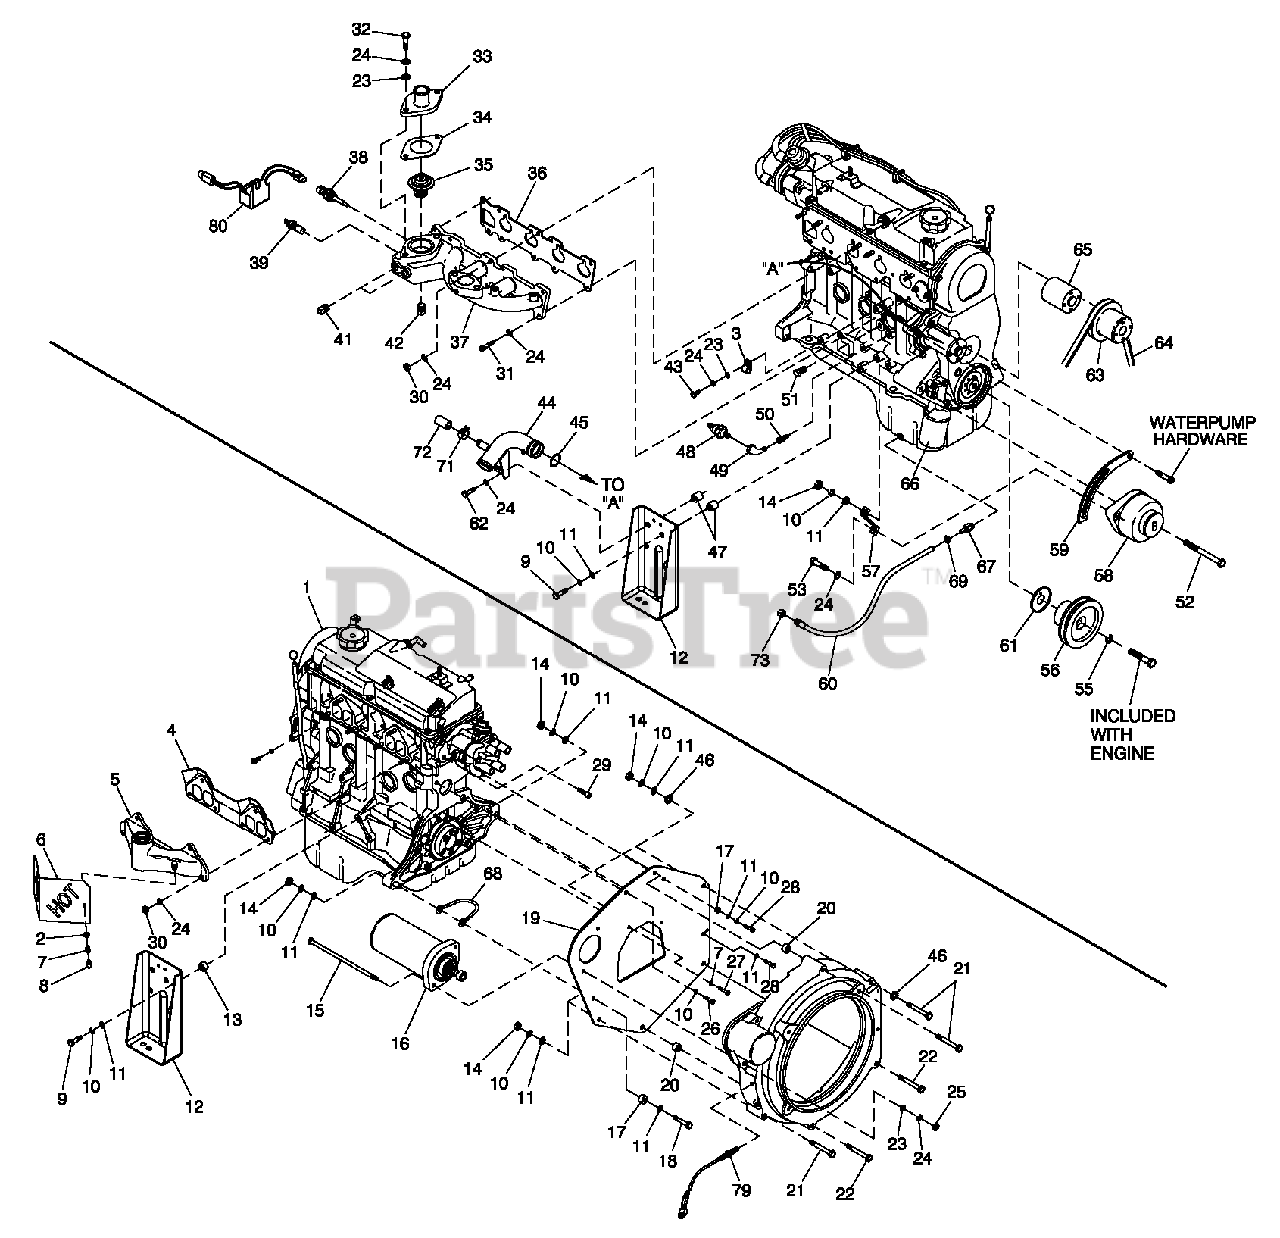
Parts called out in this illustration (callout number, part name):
1	ENGINE'1.5L
2	WASHER FLAT 1/4 ZINC
4	GASKET'EXHAUST MANIFOLD
5	MANIFOLD'EXHAUST
6	HEAT SHIELD EXH 1.5L
7	WASHER LOCK M6'1/4
8	SCREW HHC 1/4'20 X 1/2 G5
9	SCREW HHC M10'1.25 X 25 G8.8
10	WASHER'LOCK'M10
11	WASHER FLAT 3/8 ZINC
12	STAMPING ENG FOOT
13	SPACER .41 X .75 X .12 STL/ZNC
14	NUT HEX M10'1.5 G8 YEL CHR
15	SCREW SHC 5/16'18 X 2 G8.8 NZ
16	STARTER'12V
17	SPACER .56 X 1 X .37 ST/ZNC
18	SCREW HHC M10'1.5 X 60 G8.8
19	ENGINE PLATE
20	SLEEVE DOWEL BLHSG
21	SCREW HHC M10'1.5 X 70 G8.8
22	SCREW HHC M10'1.5 X 90 G8.8
23	WASHER FLAT 5/16 ZINC
24	WASHER LOCK M8'5/16
25	NUT HEX 5/16'18 STEEL
26	SCREW HHC M10'1.25 X 20 G8.8
27	SCREW HHC M6'1.0 X 16 G8.8
28	SCREW HHC M10'1.25 X 45 G8.8
29	SCREW TBH M8'1.25 X 30
30	NUT HEX M8'1.25 G8 YEL CHR
31	SCREW SHC M8'1.25 X 25 G12.9
32	SCREW HHC 5/16'18 X 1 G5
33	ADAPTER'THERMOSTAT
34	GASKET THERMOSTAT
35	THERMOSTAT 195 DEG
36	GASKET INLET MANIFOLD
37	MANIFOLD INTAKE MACHINED
38	PROBE, COOLANT LEVEL 3/8NPTF
39	SW'TMP 245 DEG 3/8 NPT
41	PLUG STD PIPE 3/8 STEEL SQ HD
42	PLUG STD PIPE 1/8 SCKT HD
43	SCREW HHC M8'1.25 X 20 G8.8
44	PIPE WATER'INLET
45	O'RING 1'1/16 X 1'5/16 X 1/8
46	WASHER SHAKEPROOF EXT 7/16 STL
47	SPACER .41 X .75 X .25 ST/ZNC
48	SWITCH OIL PRESSURE
49	ELBOW 90D STREET 1/8
50	ADAPTOR 1/8 NPTF TO 1/8'28
51	PLUG STD PIPE 1/4 STEEL SQ HD
52	SCREW HHC M10'1.5 X 110 G8.8
53	SCREW HHC M8'1.25 X 35 G8.8
55	WASHER LOCK M12
56	PULLEY'CRANKSHAFT (3600 RPM)
57	BRACKET ' ALT SUPPRT
58	DC ALTERNATOR'12V
59	ARM ADJUST ALTERNATOR
60	HOSE ASM.'OIL DRAIN
61	GUARD CRANKSHAFT 1.5L
62	SCREW CRIMPTITE 1/4'20 X 5/
63	PULLEY ' FAN 95 DIA
64	V'BELT 3/8 X 28.9D
65	SPACER PULLEY
66	FILTER OIL
67	ADAPTER DRAIN OIL
68	GROUND WIRE (STARTER)
69	CLAMP HOSE ' OIL DRAIN
70	HOSE OIL DRAIN ASSY 21"
71	CLAMP HOSE #12 .50'1.25
72	CAP ANTIFREEZE RUBBER
73	CAP HEX 1/4 NPT BRASS
79	ASSY MAGPICKUP (3/8'24 MALE)
80	ASSY PCB WATERLEVEL SNSR INTFC
